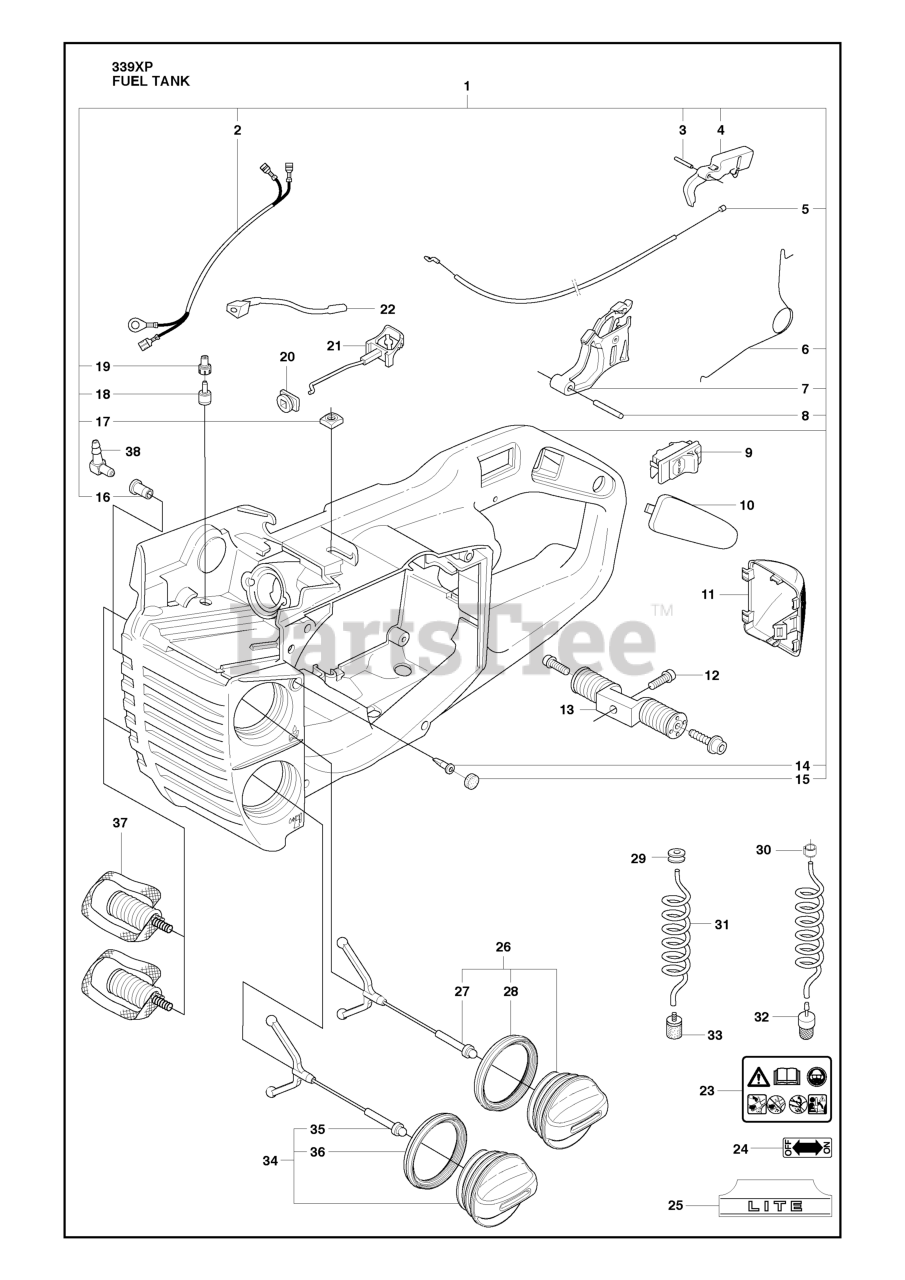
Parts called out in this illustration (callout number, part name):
1	RP TANK
2	CABLE ASSY
3	PIN 3X25
4	THROTTLE CATCH
5	THROTTLE WIRE
7	THROTTLE TRIGGER
9	START/STOP SWITCH
11	SPARK PLUG COVER
13	VIBRATION ABSORBER
14	VALVE-CHECK (DUCKBILL)
18	FUEL TANK VENT
21	CHOKE CONTROL
24	DECAL
25	DECAL
26	TANK CAP
28	SEALING
29	FUEL TANK BUSHING
30	CLAMP
31	FUEL HOSE
32	OIL PLUMMET
33	RP FUEL FILTER
34	TANK CAP LIGHT GRAY
36	SEALING
37	ANTI-VIBE ELEMENT
